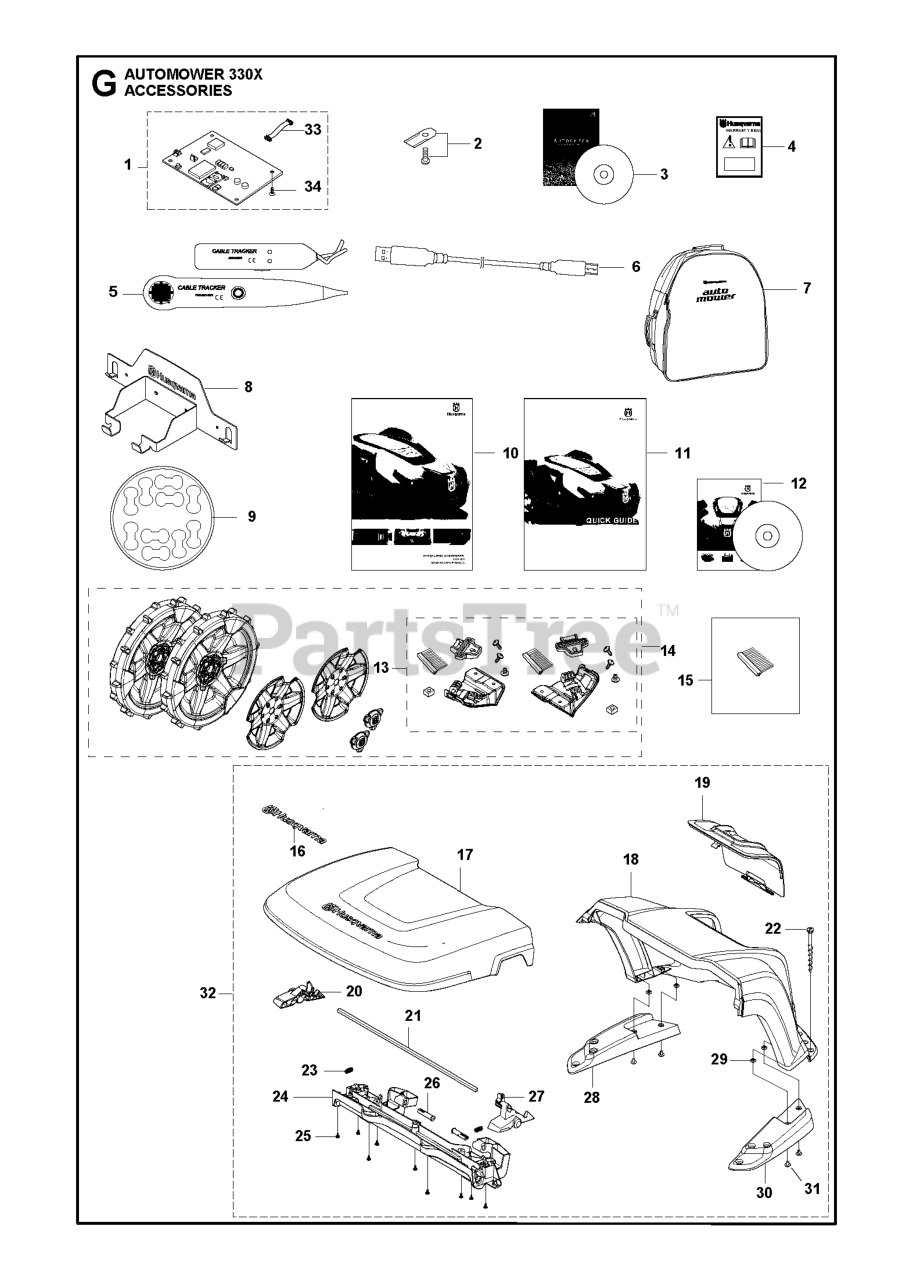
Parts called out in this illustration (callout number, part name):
1	POWER UNIT POWER SUPPLY TYPE F
2	STAPLE 100 PCS, BLISTER
2	STAPLE 100 PCS
3	SCREW 3 PCS, BLISTER PACK
4	LOOM LOW VOLTAGE CABLE 20 METE
5	LOOM LOW VOLTAGE CABLE 10 METE
5	LOOM LOW VOLTAGE CABLE 3 METER
6	WIRE BOUNDARY 150M
6	WIRE 150M, BLISTER
7	WIRE 250M
8	WIRE 500M
9	BRAKER
9	CONNECTOR 5 PCS, BLISTER
10	SPLICE KIT
10	COUPLER SPLICER, 5 PCS,
10	COUPLER SPLICER, 100 PCS
11	RULER / CENTIMETERS
12	LABEL SECURITY
